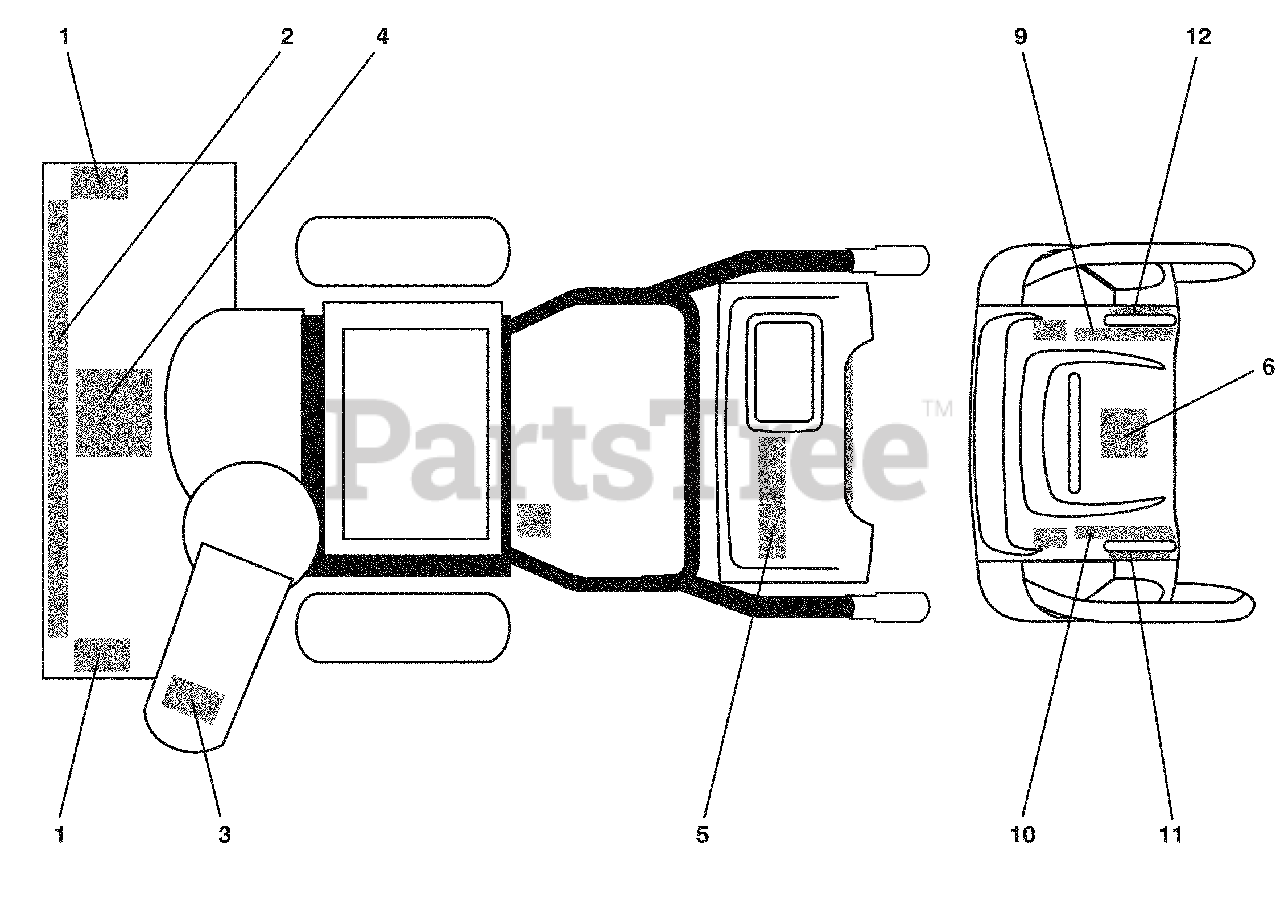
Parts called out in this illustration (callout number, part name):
1	DECAL, DANGER
2	DECAL, HUSQ USA
3	DECAL, DANGER, DEFLECTOR
4	DECAL, DANGER
5	DECAL, HUSQ USA
6	DECAL, INSTRUCTION
9	DECAL, SPEED CONTROL
10	DECAL, REMOTE DEFLECTOR
11	DECAL, LH TRIGGER
12	DECAL, RH TRIGGER
